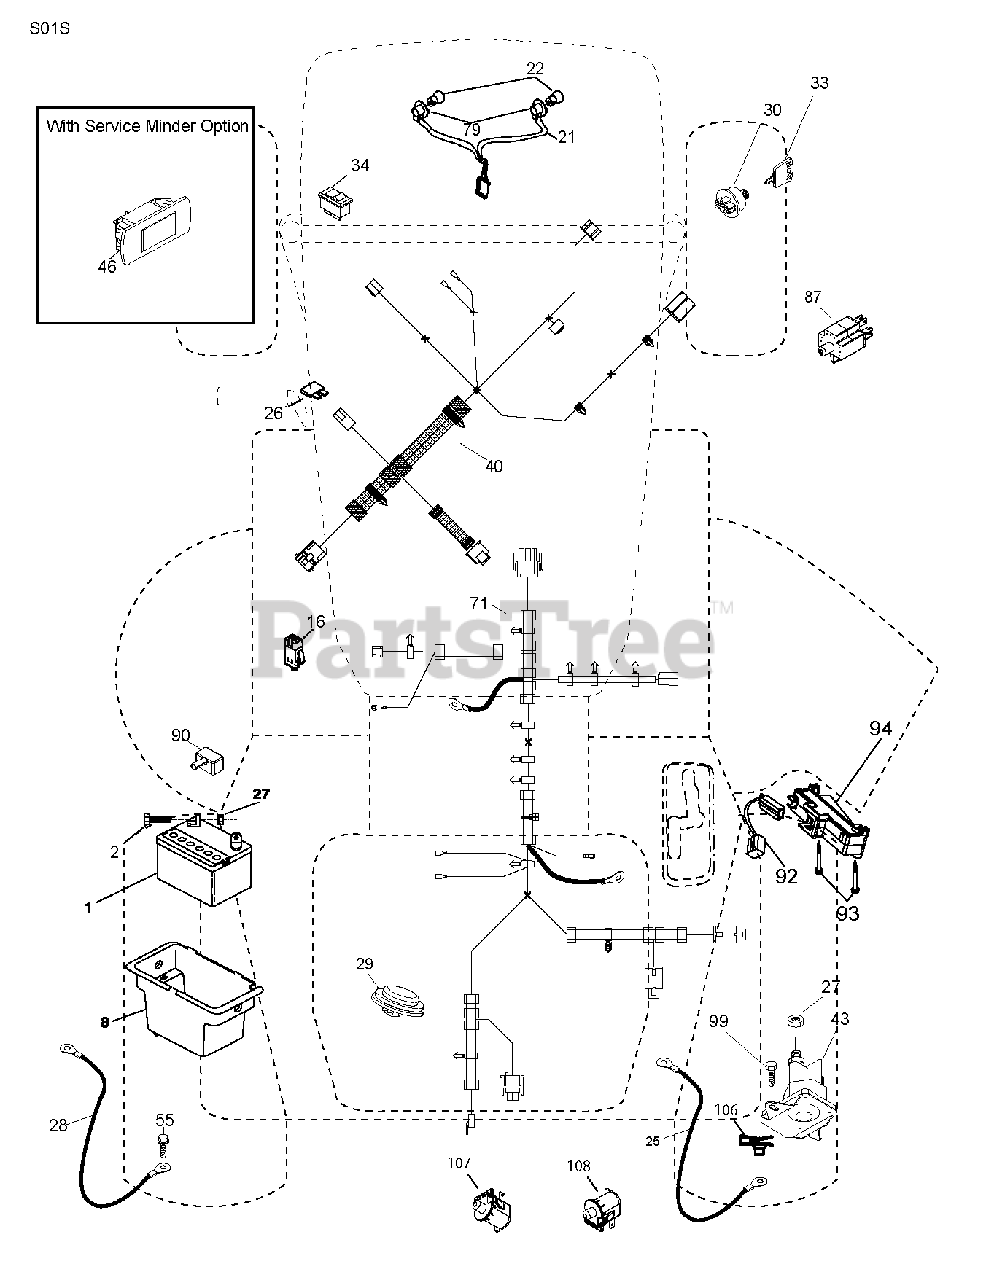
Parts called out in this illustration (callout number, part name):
8	BOX.BATTERY.LT/SRD
16	SWITCH INTERLOOK PUSH-IN
21	HARNESS.LIGHT W/4152J BULBS
25	CABLE.BATTERY.20.RED.8 AWG
27	NUT
28	Battery Ground Cable, Rear 8 Ga
29	SWITCH.SEAT.DELTA.OPC.
30	SWITCH.IGN.DELTA.W.LGH.ROS
33	KEY.CHAIN.BLISTER.PACK.GEN.INT
40	HARNESS.ELECTRICAL.DASH.SRD
43	SOLENOID.W/BRASS.PLUNG
55	SCREW 5/16"
71	HARNESS.ELECTRIC.CHASSIS.SRD
79	BULB HOLDER ASM.
87	Railmount Switch, No-Nc-Nc
90	COVER.TERMINAL.BATTERY
92	HARNESS.PIGTAIL.CONSLE
93	SCREW.PLASTITE
94	MODULE.REVERSE.ROS
99	SCREW HEXWSHR 1/4-20X3/4
107	Snapmount Switch, No #2
108	SWITCH.SNAPMOUNT.NC
